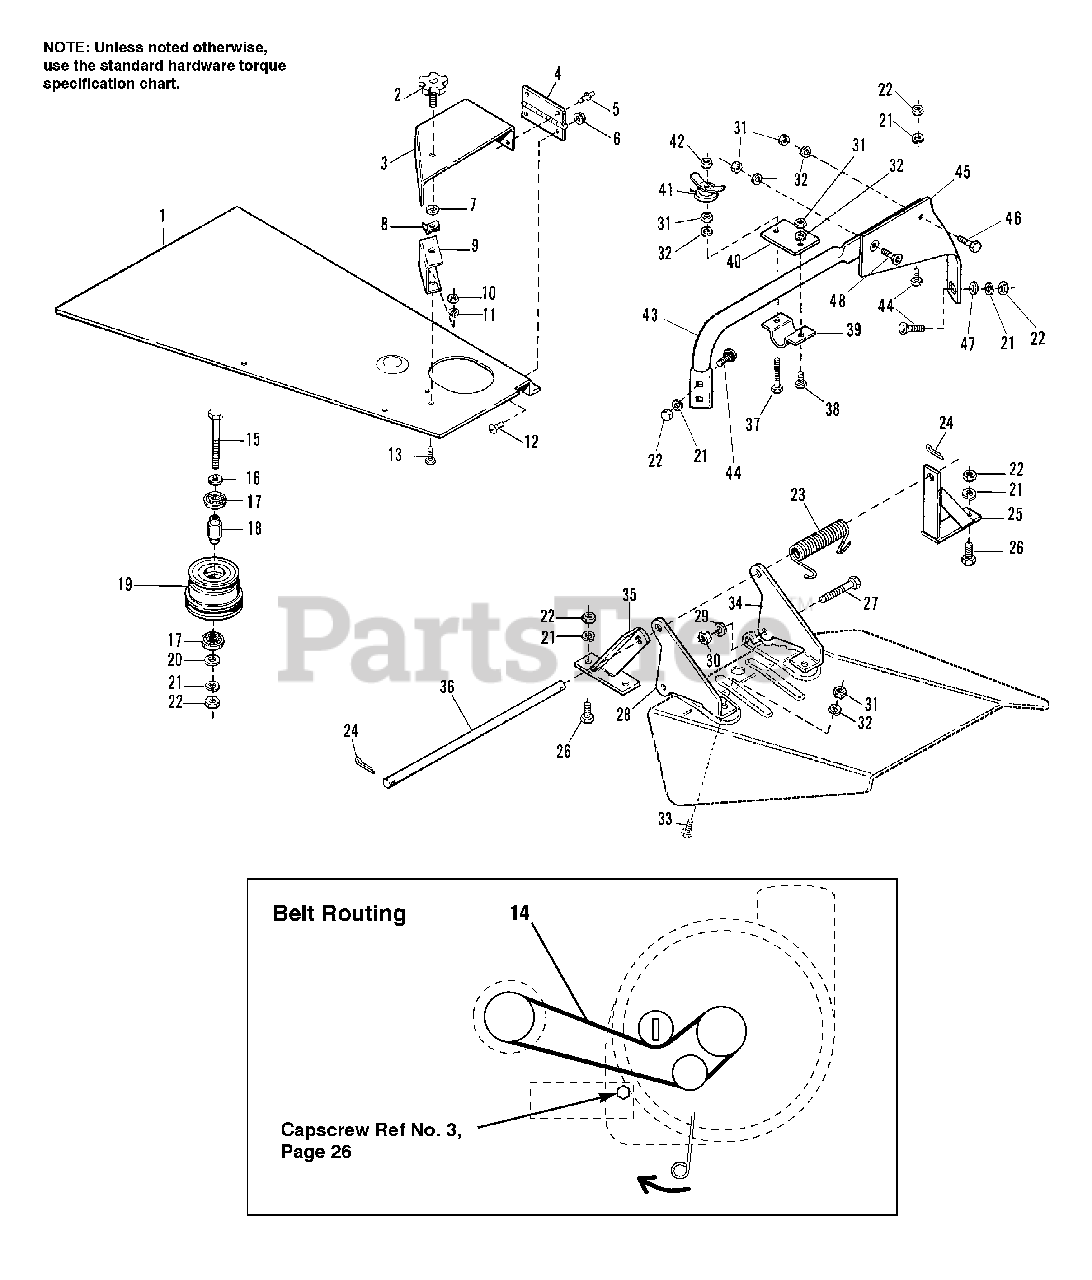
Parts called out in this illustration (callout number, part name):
1	COVER, LH Mower
2	KNOB, Plastic
3	COVER ASSEMBLY
5	POP-RIVET, 3/16 x 5/16
6	NUT, Hex Flange, #10-32
7	NUT, Push, 5/16
8	NUT, Speed, 5/16-18
9	BRACKET, Belt Cover
10	NUT, Hex, 1/4-20
11	WASHER, Lock, 1/4
12	SCREW, Rd Hd Machine, #10-32 x 3/8
13	CAPSCREW, Hex Hd, 1/4-20 x 1/2
14	V-BELT
15	CAPSCREW, Hex Hd, 3/8-16 x 3-1/4
16	WASHER, 3/8
18	SPACER, Pulley
21	WASHER, Lock, 3/8
22	NUT, Hex, 3/8-16
23	SPRING, Torsion
24	PIN, Cotter, 3/32 x 3/4
25	HINGE ASSEMBLY, Rear
26	CAPSCREW, Hex Hd, 3/8-16 x 1
27	CAPSCREW, Hex Hd, 7/16-14 x 2-3/4
28	BRACKET, LH Pivot
29	WASHER, Lock, 7/16
30	NUT, Hex, 7/16-14
31	NUT, Hex, 5/16-18
32	WASHER, Lock, 5/16
33	CAPSCREW, Hex Hd, 5/16-18 x 7/8
34	BRACKET, RH Pivot
35	HINGE ASSEMBLY, Front
37	CAPSCREW, Hex Hd, 5/16-18 x 2-1/2
38	CAPSCREW, Hex Hd, 5/16-18 x 5/8
39	CLAMP, Lower
40	CLAMP, Upper
41	NUT & CUP ASSEMBLY
42	NUT, Hex Lock, 5/16-18
43	BRACE, Bracket Support
44	CARRIAGE BOLT, 3/8-16 x 1
45	BRACKET, Support
46	CAPSCREW, Hex Hd, 5/16-18 x 1-1/4
47	WASHER, 3/8
48	SCREW, Flat Hd, Hex Socket, 5/16-18 x 1-1/4
